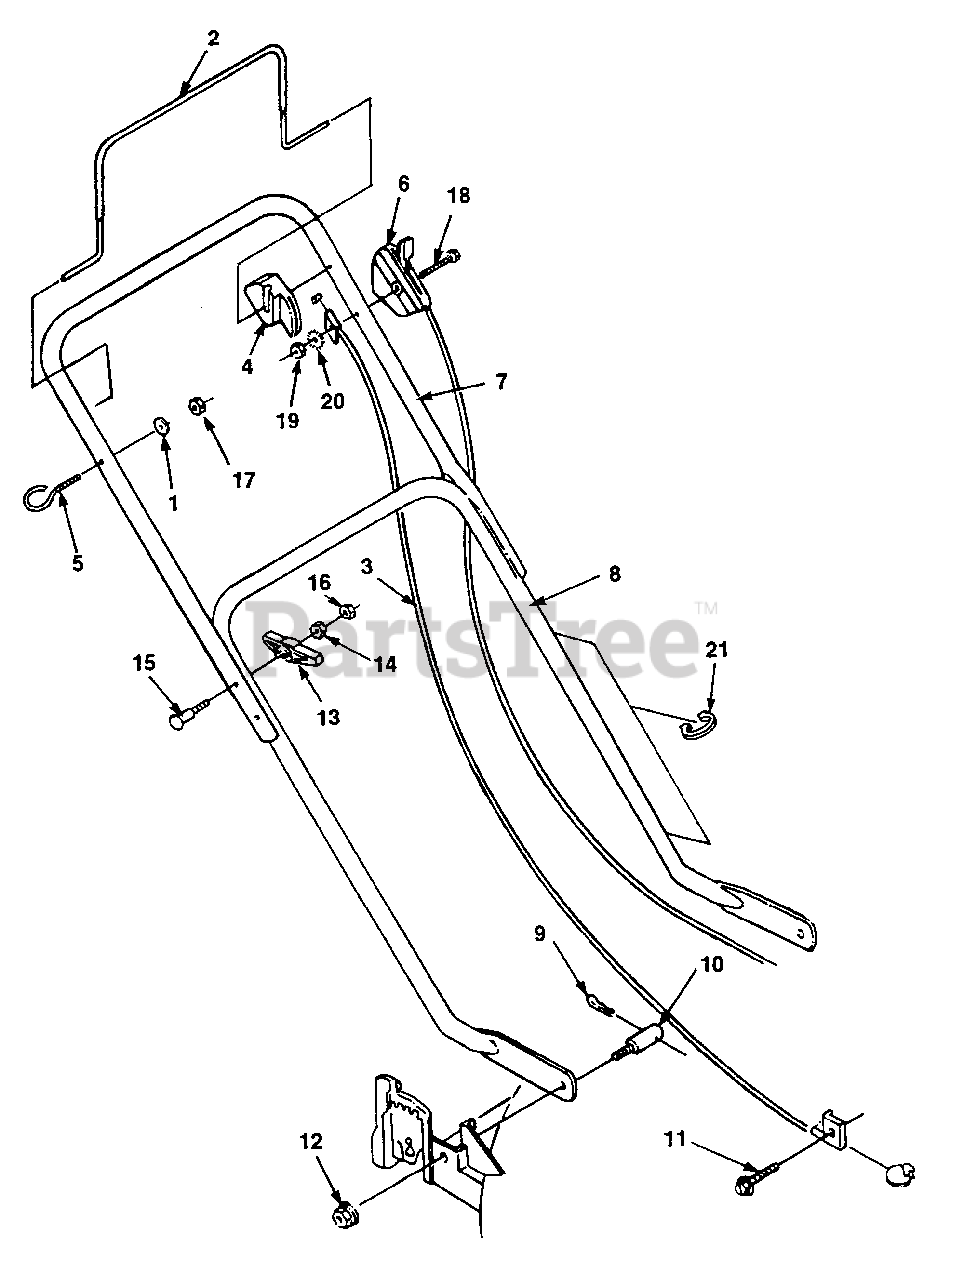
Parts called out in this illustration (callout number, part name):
1	WASHER- Curve
2	BAIL- Brake control
3	CONTROL- Manual start
4	ACTUATOR- L.H.
6	CONTROL- Throttle
7	HANDLE- Upper
8	HANDLE- Lower
9	PIN- Hair
11	SCREW- Hex hd. (10-32 x 3/8")
12	NUT- Flanged (5/16-18)
13	KNOB- Handle
14	NUT- Hex (5/16-18)
16	NUT- Hex lock (5/16-18)
17	NUT- Hex lock (1/4-20)
18	SCREW- Hex cap (1/4-20 x 2")
19	NUT- Hex (1/4-20)
20	WASHER- External tooth
21	CLAMP- Double
